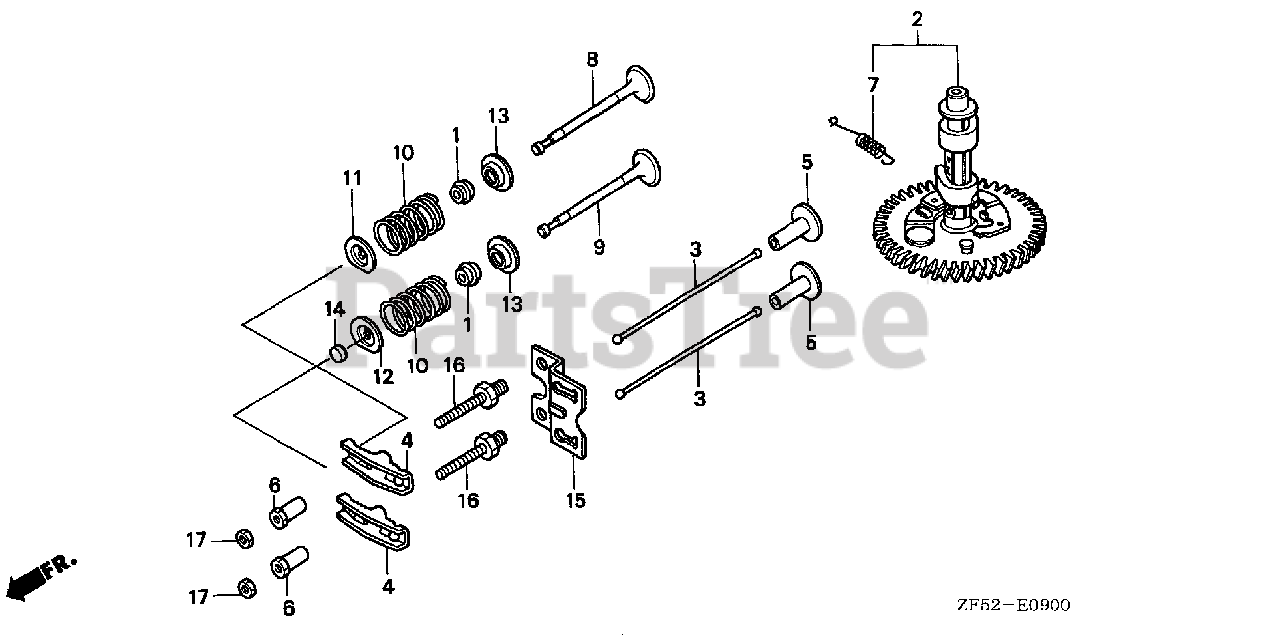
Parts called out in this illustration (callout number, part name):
1	SEAL, VALVE STEM
2	CAMSHAFT ASSY.
3	ROD, PUSH
4	ARM, VALVE ROCKER
5	LIFTER, VALVE
6	PIVOT, ROCKER ARM
7	SPRING, WEIGHT RETURN
8	VALVE, IN.
9	VALVE, EX.
10	SPRING, VALVE
11	RETAINER, IN. VALVE SPRING
12	RETAINER, EX. VALVE SPRING
13	SEAT, VALVE SPRING
14	ROTATOR, VALVE
15	GUIDE, PUSH ROD
16	BOLT, PIVOT (8MM)
17	NUT, PIVOT ADJUSTING
